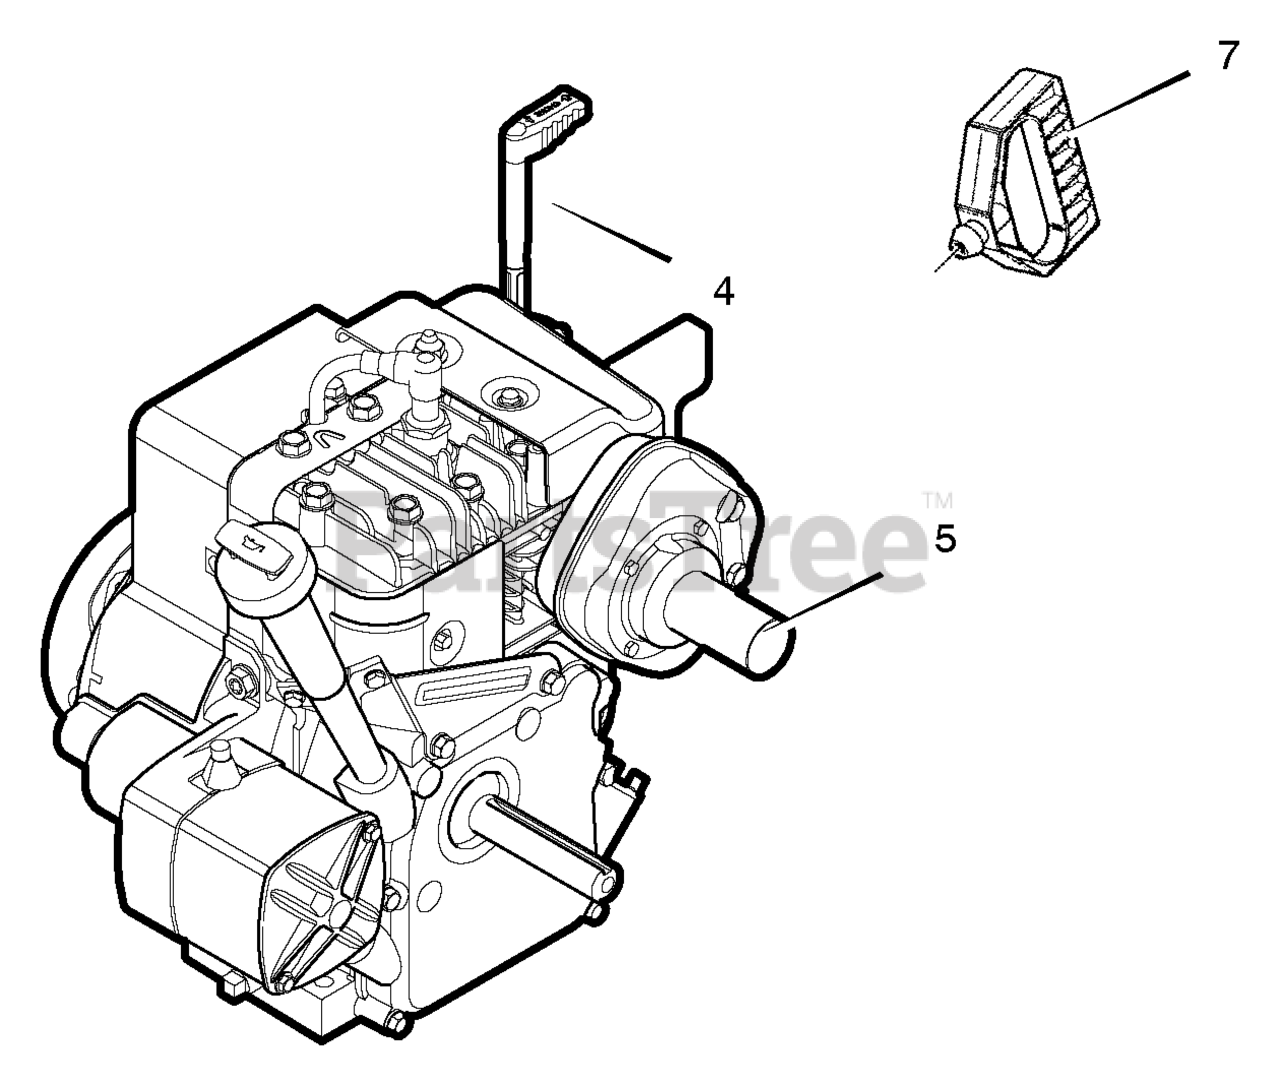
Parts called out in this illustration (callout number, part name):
4	Lever, Choke *
5-1	Muffler *
5-2	Gasket, Muffler *
5-3	Bolt, Muffler
5-4	Washer, Split Lock
5-5	Nut, Hex 5/16-18
5-6	Bolt, Hex 5/16-18
7	Grip, Mitten
